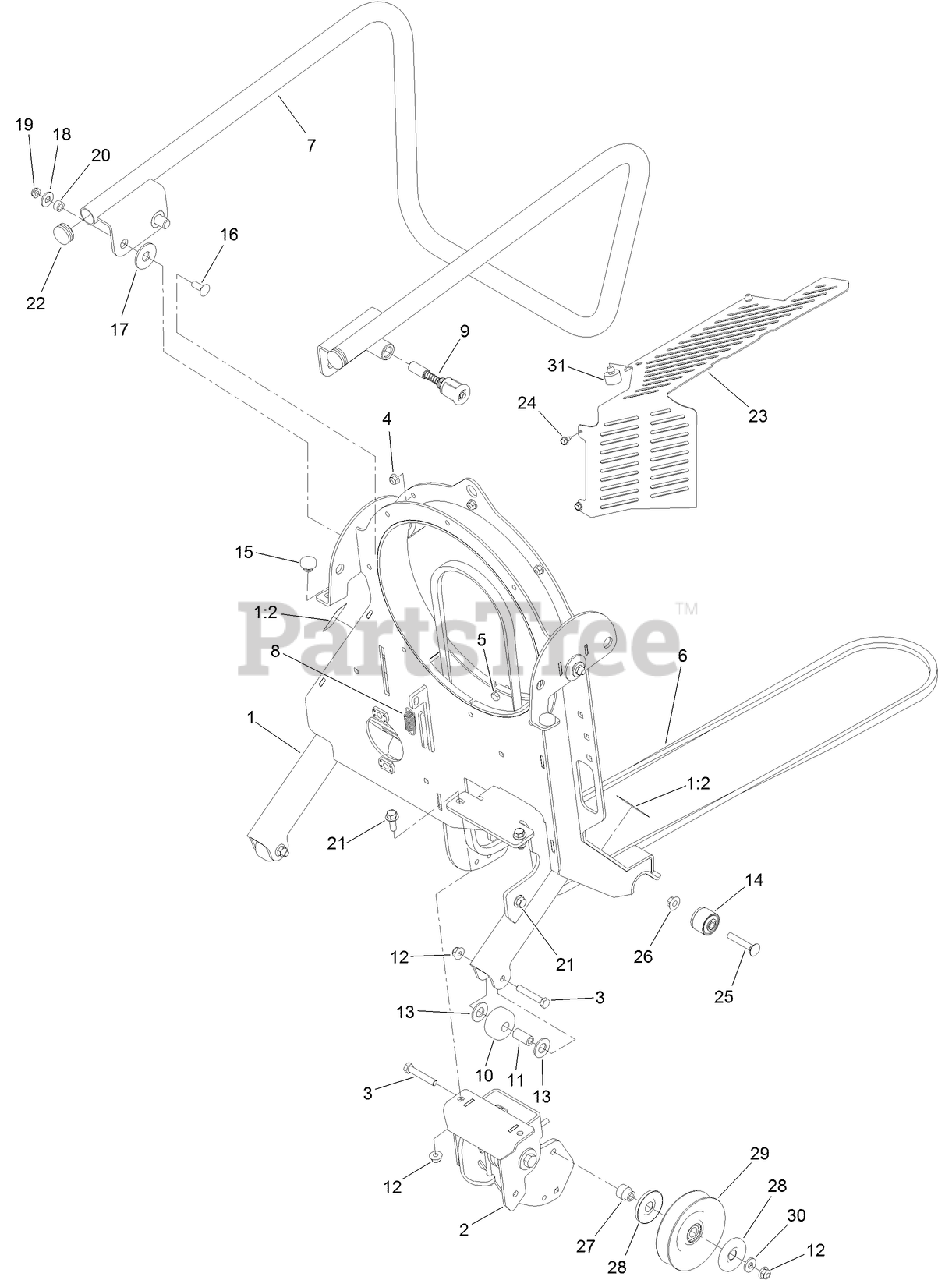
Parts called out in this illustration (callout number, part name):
1	BLOWER FRAME SERVICE ASM
1:2	DECAL-DANGER
2	IDLER TORSION ASM
3	SCREW-HH
4	NUT-HF, NI
5	SCREW-HH
6	BELT-V
7	BLOWER KICKSTAND ASM
8	SPRING-BRAKE
9	PIN-SPRING
10	ROLLER
11	SPACER
12	NUT-HF, NI
13	WASHER-FLAT
14	PIVOT-MOUNT ASM
15	BUMPER-RUBBER
16	SCREW-CARR
17	SPACER
18	WASHER-FLAT
19	NUT-LOCK, NI
20	SPACER
21	SCREW-HHF
22	CAP-TUBE
23	GUARD-MUFFLER
24	SCREW-HWHTF
25	SCREW-CARR
26	NUT-HF
27	BUSHING-IDLER
28	SHIELD-GUARD, DUST
29	PULLEY-IDLER
30	WASHER-SPACER
31	BUMPER-GROMMET
